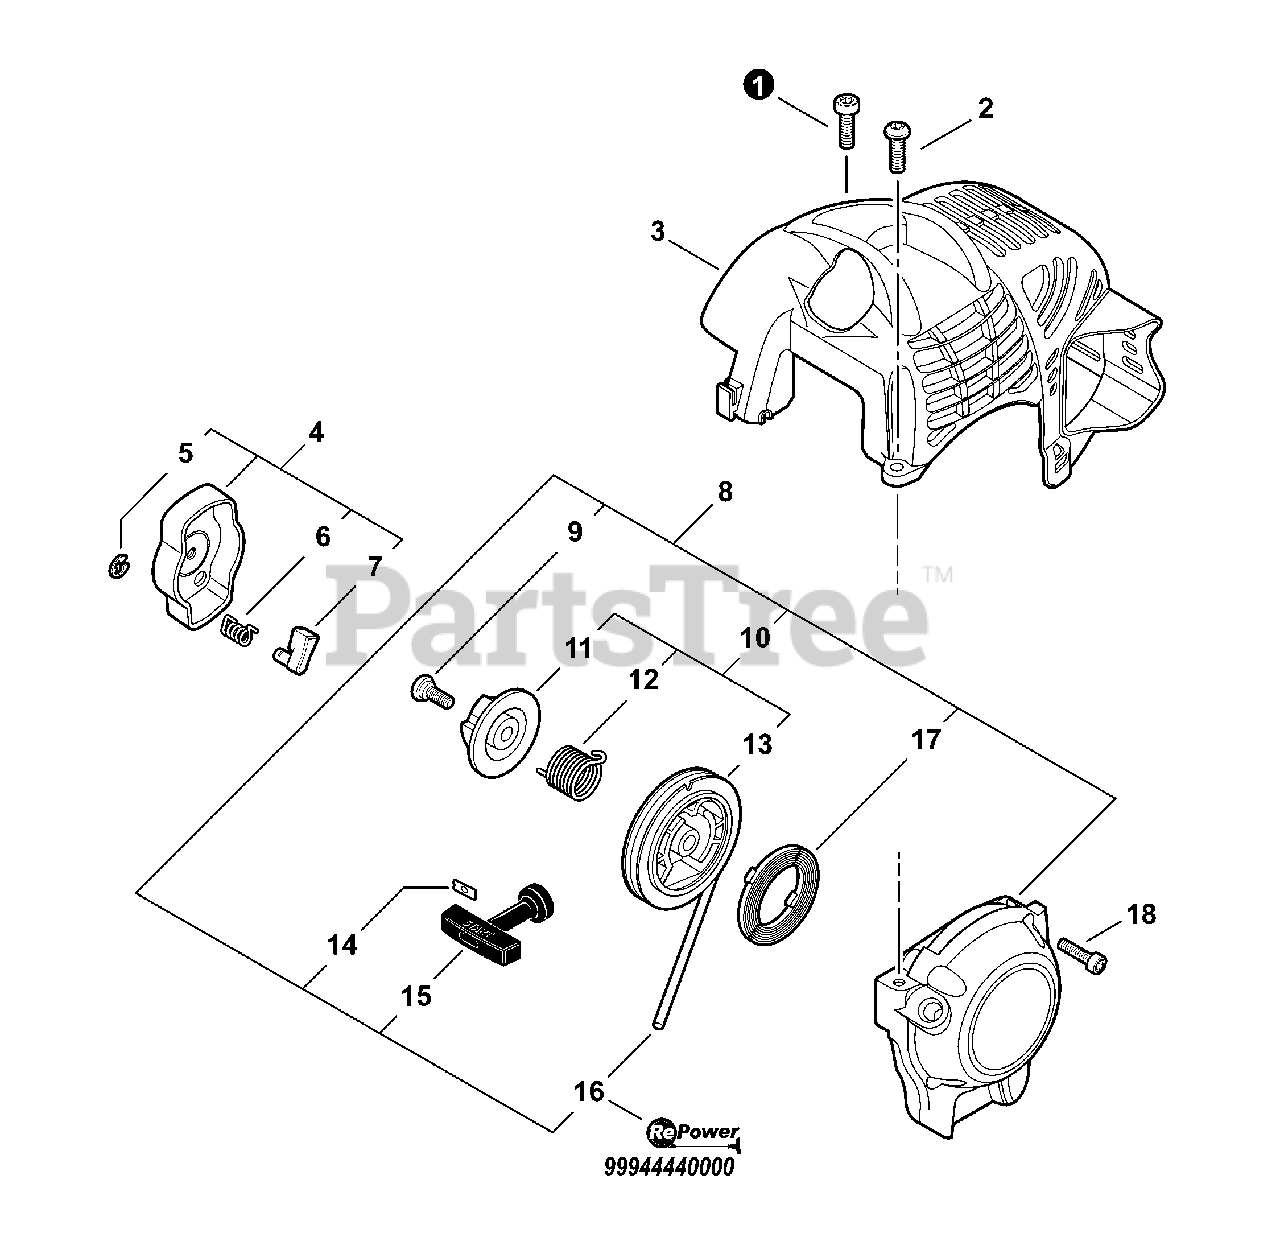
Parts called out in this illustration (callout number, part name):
1	SCREW - 5×16 -- TORX
2	SCREW - 5×16 -- TAPPING
3	COVER, ENGINE
4	STARTER PAWL ASY
5	RING, RETAINING - 4
6	SPRING, RETURN
8	STARTER ASY
9	SCREW
10	ROPE REEL KIT
11	PLATE, CAM
12	SPRING, DAMPER
13	ROPE, REEL
14	RETAINER, ROPE
15	GRIP, STARTER
16	ROPE, STARTER
17	SPRING, REWIND
18	SCREW - 4×16 -- TORX
